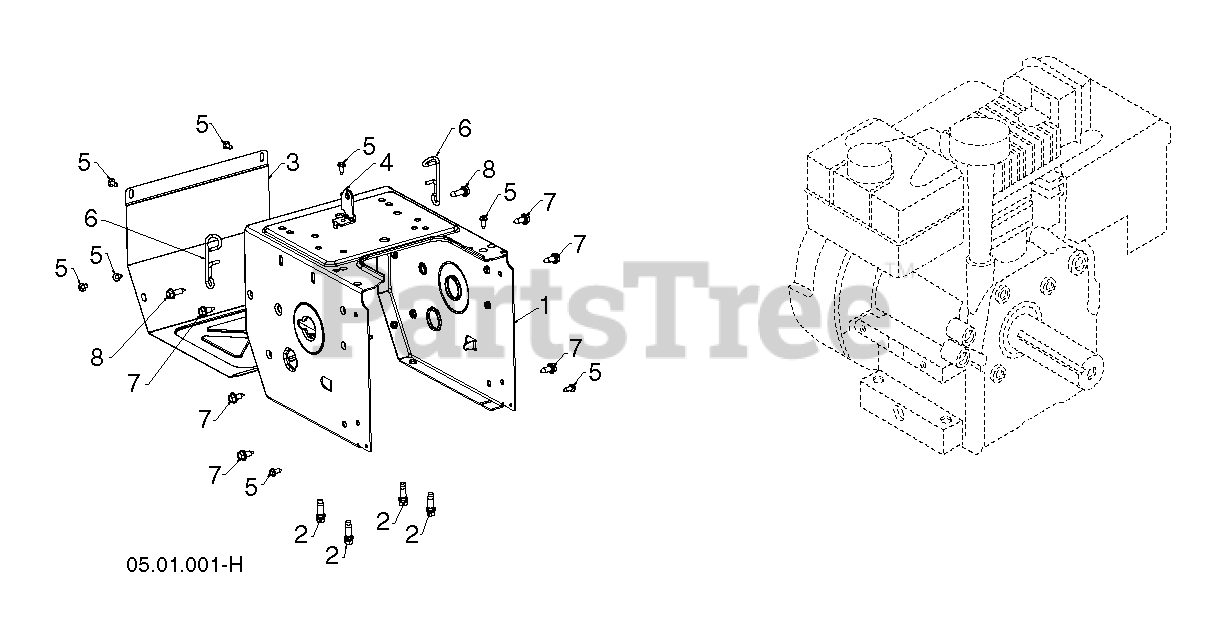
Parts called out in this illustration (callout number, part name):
1	FRAME MS 428
2	Hex Head Thread Rolling Screw 3/8-16 x 1-1/8 (AYP part number)
3	FRAME.COVER.SNOW.BLACK
4	BRACKET.SHIFTER.BZP
5	SCREW.HEX HEAD W/COLLAR 1/4-20
6	WIREFORM.SUPPORT.CABLE
7	BOLT.HEX.HD.WASHER.5/16-18X.75
8	SCREW HEX_SERR_HD_5_16-18X1.0
